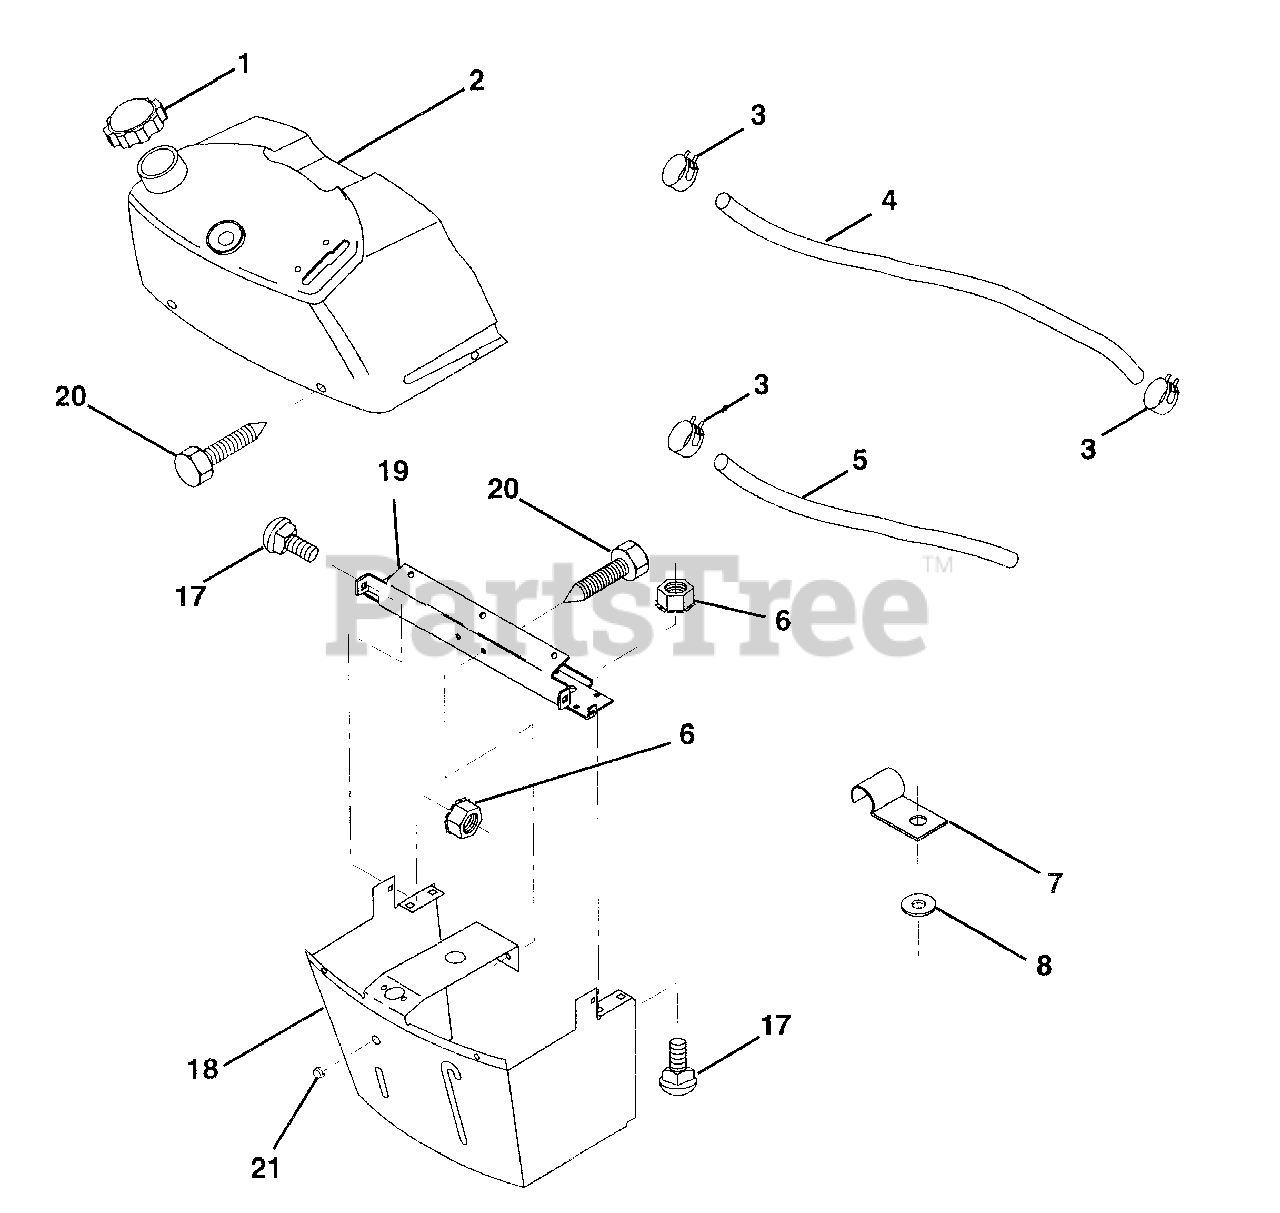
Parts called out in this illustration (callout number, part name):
1	Cap, Fuel
2	Dashboard & Fuel Tank Assembly
3	Clamp, Hose
4	Line, Fuel
5	Line, Fuel
6	Nut, Hex, Keps 1/4-20
7	Clip, Fuel Line
8	Washer 9/32 x 3/4 x 16 Gauge
17	Bolt, Carriage 1/4-20 x 1/2 Grade 5
18	Support Assembly, Dash
19	Brace, Cross
20	Screw, Self-tapping 1/4-20 x 1/2
21	Plug, Dome, Black
